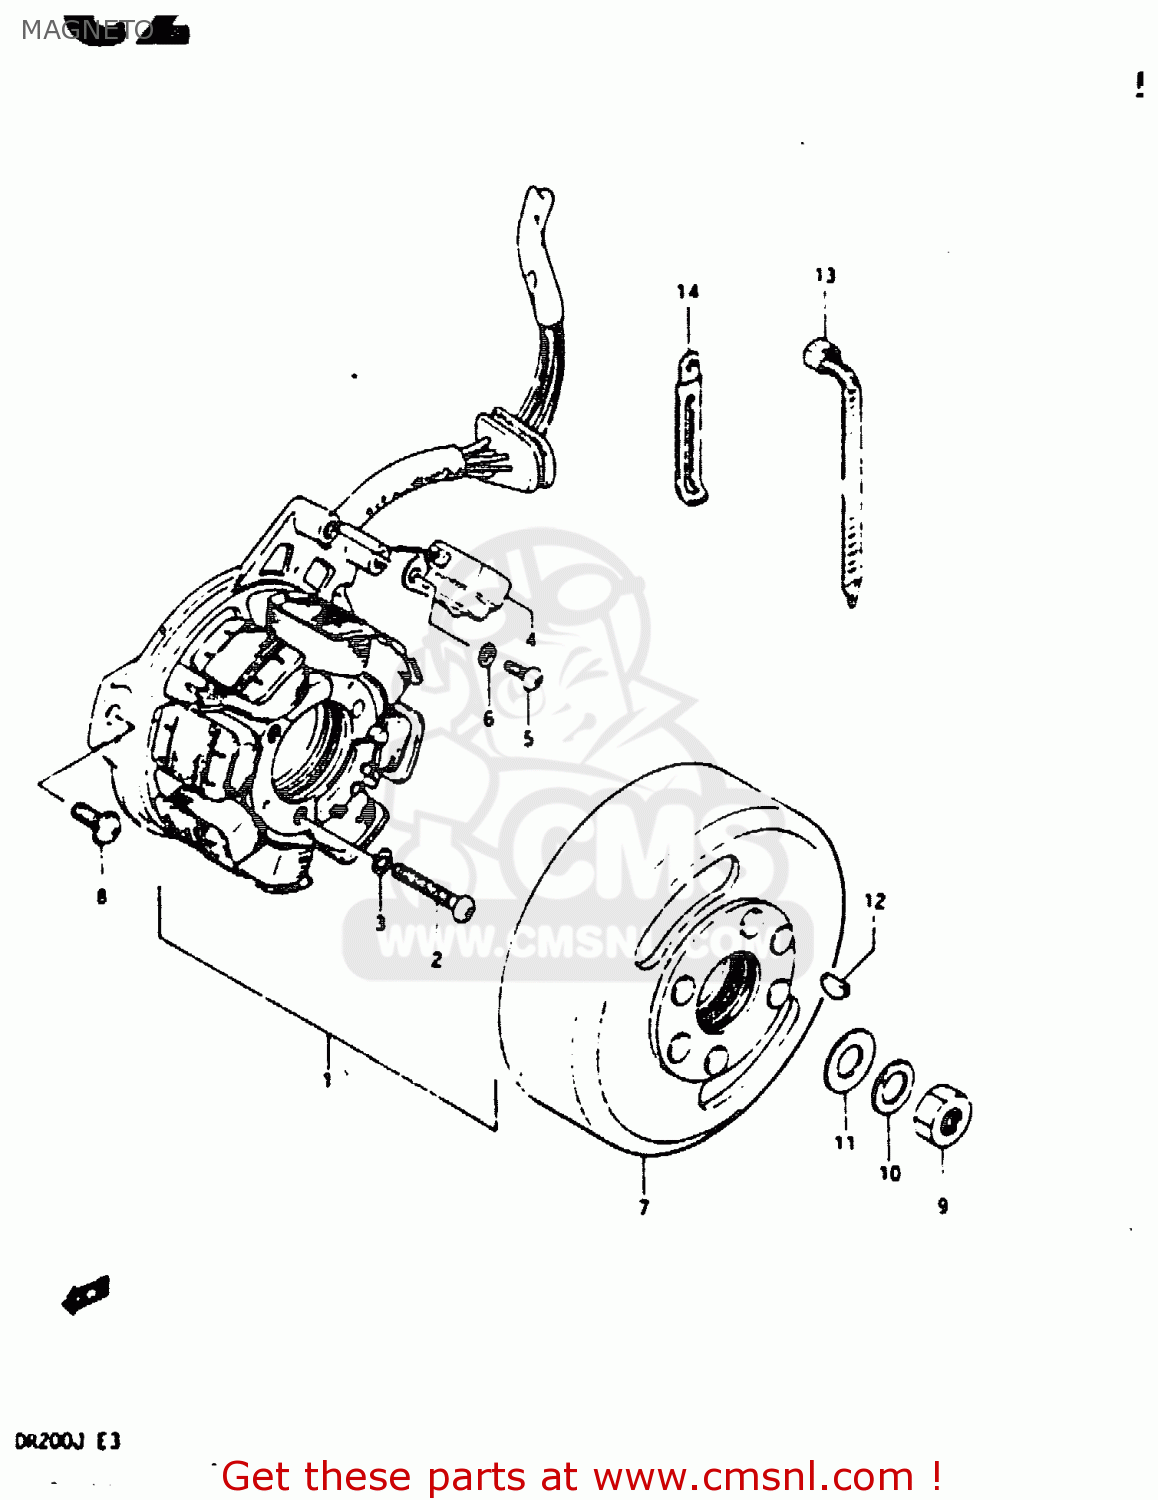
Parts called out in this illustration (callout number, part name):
1	STATOR ASSEMBLY
2	SCREW
3	LOCK WASHER
4	COIL,PICK UP
5	SCREW
6	WASHER,LOCK 4M
7	ROTOR ASSEMBLY
8	SCREW(5X14)
9	NUT (10MM)
10	WASHER,LOCK,10
11	WASHER
12	KEY
13	CLAMP(L:125)
14	CLAMP
